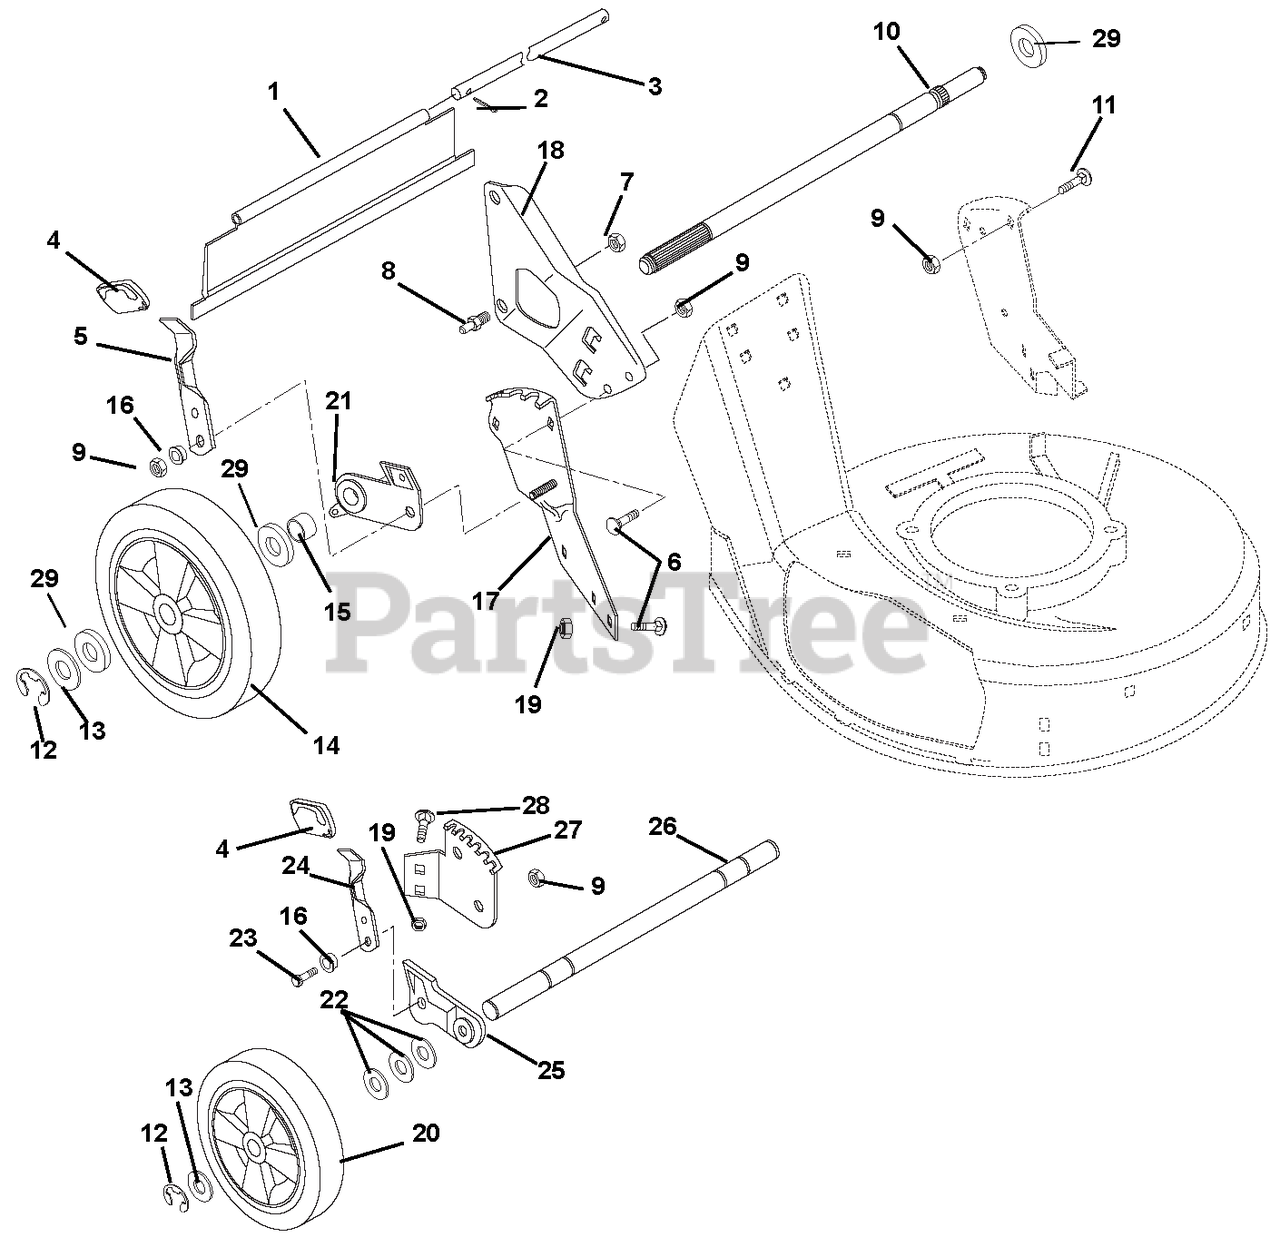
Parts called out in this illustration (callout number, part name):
1	REAR PROTECTIVE GUARD, S.P.
1	REAR PROTECTIVE GUARD, PUSH
2	@PIN-CTR .06X.50 EXTPRSQCT YWZ
3	ROD
5	LEVER, HEIGHT ADJUSTMENT
6	@BLT-RHDSSQNK .31-18X.62 G5YZ
7	@NUT-LK-CTR .38-16 YWZC
8	HANDLEBAR STUD
9	@NUT-LK-TOP-FLG .31-18 YWZC
10	REAR AXLE,5/8 DIA
10	REAR AXLE-PUSH MOWER MM
11	BLT-RDHDSQNK .31-18X1.0 SHTYZ
12	RG-RTNG-EXT .500X.042 (E)
13	WSHR-FL-STL .505X.880X.072 YWZ
14	WHL, LH 10.50"
14	WHEEL, 10.3" OD X 2" WIDE LHS
14	WHL, RH 10.50"
14	10 1/2 TIRE SKIN
15	SPACER TUBE, SELF PROPEL
15	SPACER TUBE PUSH RH
16	BSHG-FLG .32X.500X.344X.880
17	QUADRANT, REAR LH
17	QUADRANT, REAR RH
18	RH HANDLEBAR MTG. BRKT
18	LH HANDLEBAR MTG. BRKT
19	@NUT-LK-TOP-FLG .31-18 YWZC
20	WHL 7.50" .50 BORE, 1.50 HUB
21	REAR BRACKET & BEARING ASSY LH
21	REAR BRACKET & BEARING ASSY RH
21	REAR BRACKET & BEARING ASSEMBL
22	WSHR-FL-STL .52X.827X.062 YWZC
23	@BLT-HEX .31-18X1.00 GR5 YWZC
24	FRONT HEIGHT ADJUSTMENT LEVER
25	LEFT ADJUSTOR BRACKET ASSEMBLY
25	RIGHT ADJUSTOR BRACKET ASSEMBL
26	FRONT AXLE
27	FRONT QUADRANT, LH
27	FRONT QUADRANT, RH
28	@BLT-RDHDSQNK .31-18X.50 G5YZ
29	SPACER .531 X 1.00 X .225
